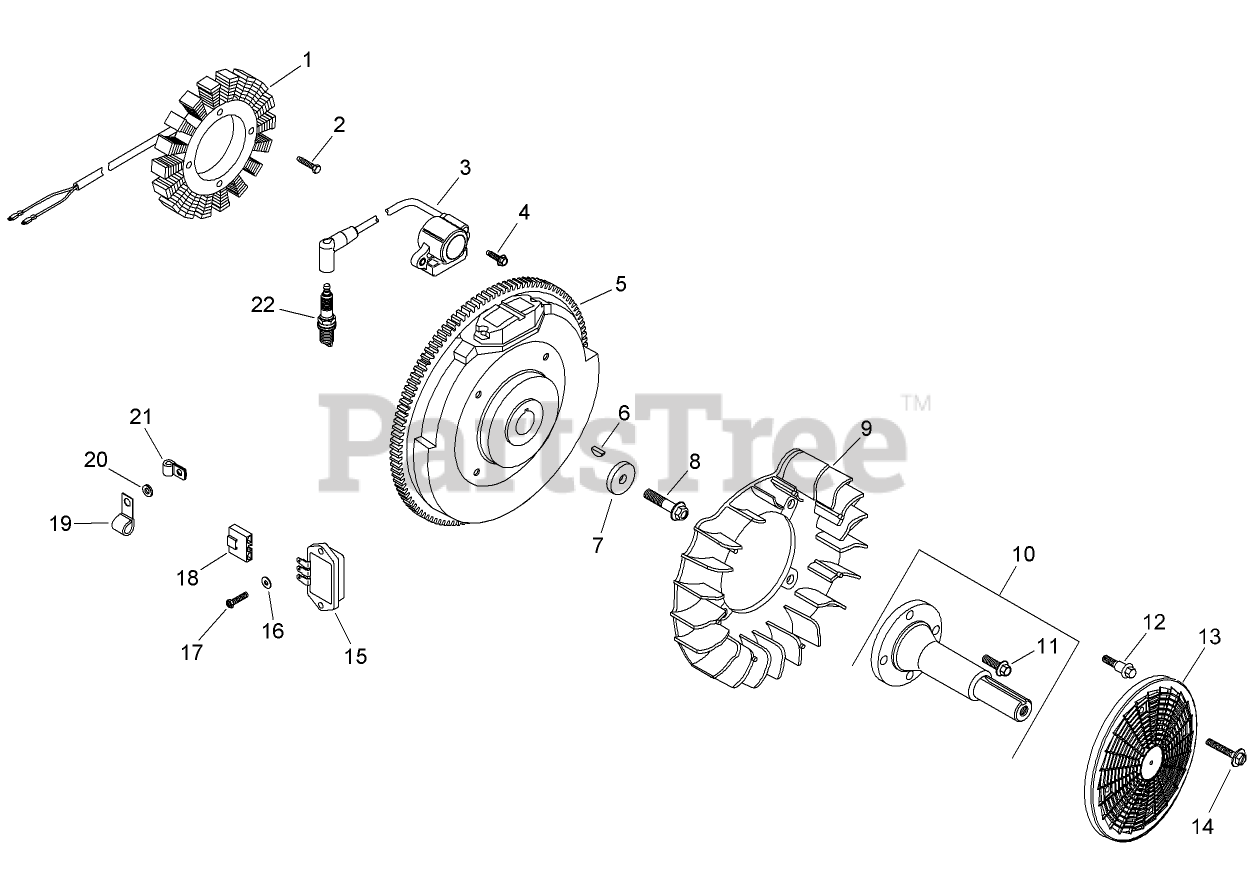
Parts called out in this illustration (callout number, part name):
1	Stator Kit (15 AMP) (INCLUDES 25 452 01-S)
2	SCREW-THREAD FORMING (M5X0.8X25)
3	MODULE-IGNITION (C D I FIXED)
4	SCREW-FLANGE, THREAD FORMING (M5X.8X20)
5	FLYWHEEL
6	KEY (3/16 X 5/8)
7	WASHER-FLAT (13/32)
8	SCREW-FLANGE (M10X1.5X45)
9	Fan
10	Shaft-Drive, Front (INCLUDES 11)
11	Screw-HF (M8x1.25x25)
12	BOLT-SHOULDER (M6x1.0x16)
13	Screen-Grass
14	SCREW-FLANGE, SEMS (M4X.7X25)
15	Rectifier-Regulator
16	WASHER-FLAT (.22)
17	SCREW-PHL HD (11-16X.88)
18	Connector (3 contact)
19	CLIP-CABLE
20	WASHER-FLAT (1/4)
21	CLAMP-INSULATED
22	SPARK PLUG (PRO SERIES)
